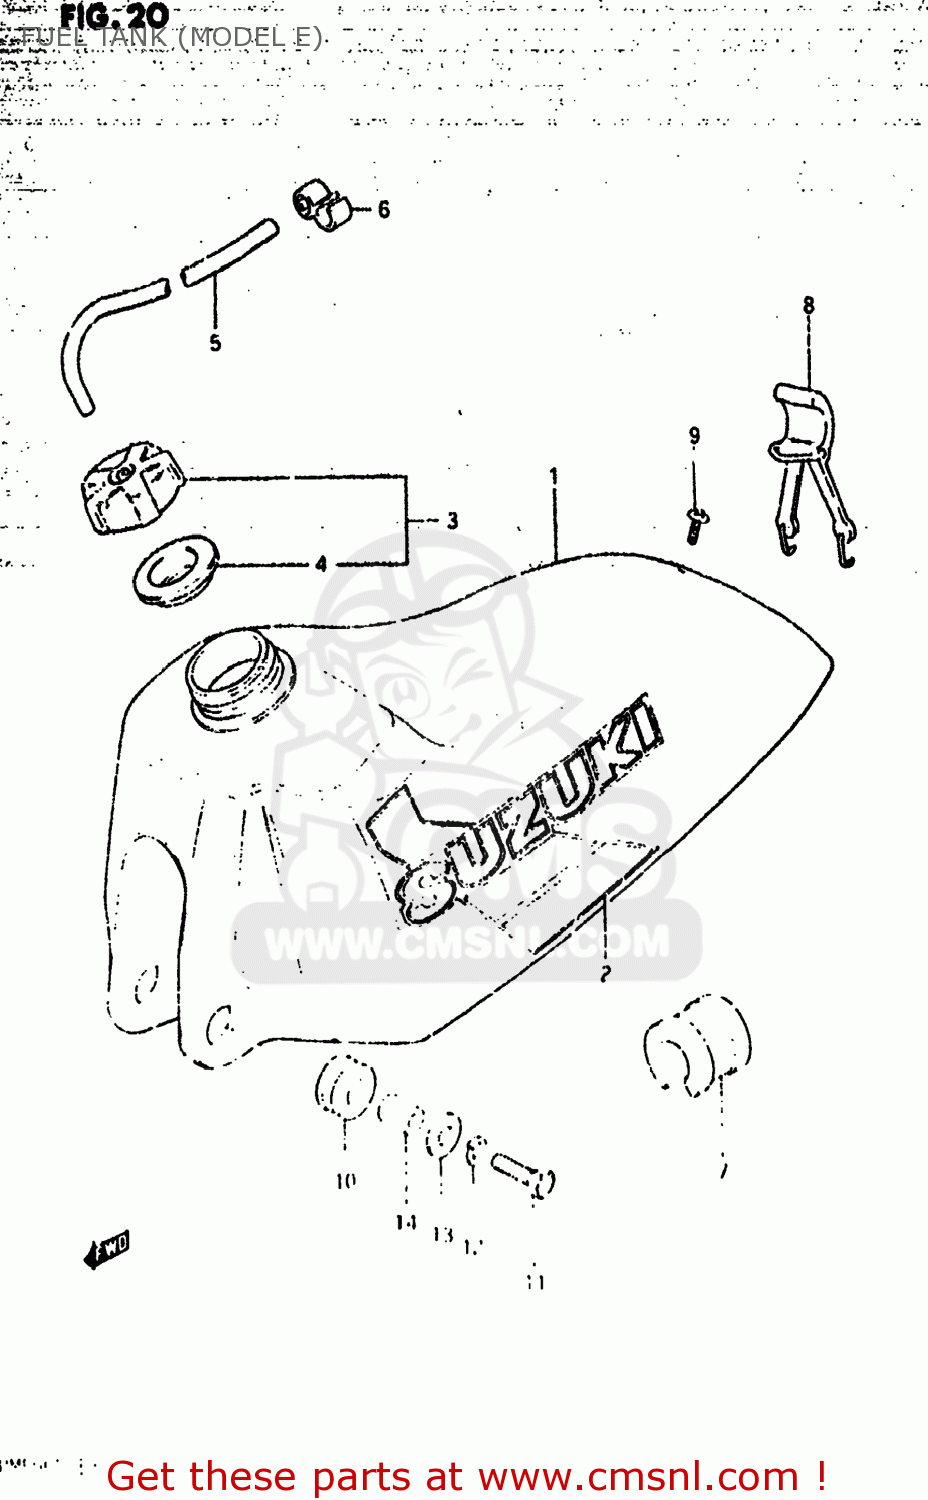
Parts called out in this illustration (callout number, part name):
1	TANK ASSEMBLY,FUEL
2	TAPE SET,FUEL TANK
3	CAP SET,FUEL TANK
4	GASKET,FUEL TANK CAP (NAS)
5	HOSE
6	CLAMP,BREATHER HOSE
7	CUSHION,FUEL TANK UPR
8	BAND,FUEL TANK,REAR
9	SCREW (6X15)
10	CUSHION
11	BOLT (8X30)
12	LOCK WASHER
13	WASHER (8.5X26X1.2)
14	SPACER (8.8X12X13.5)
